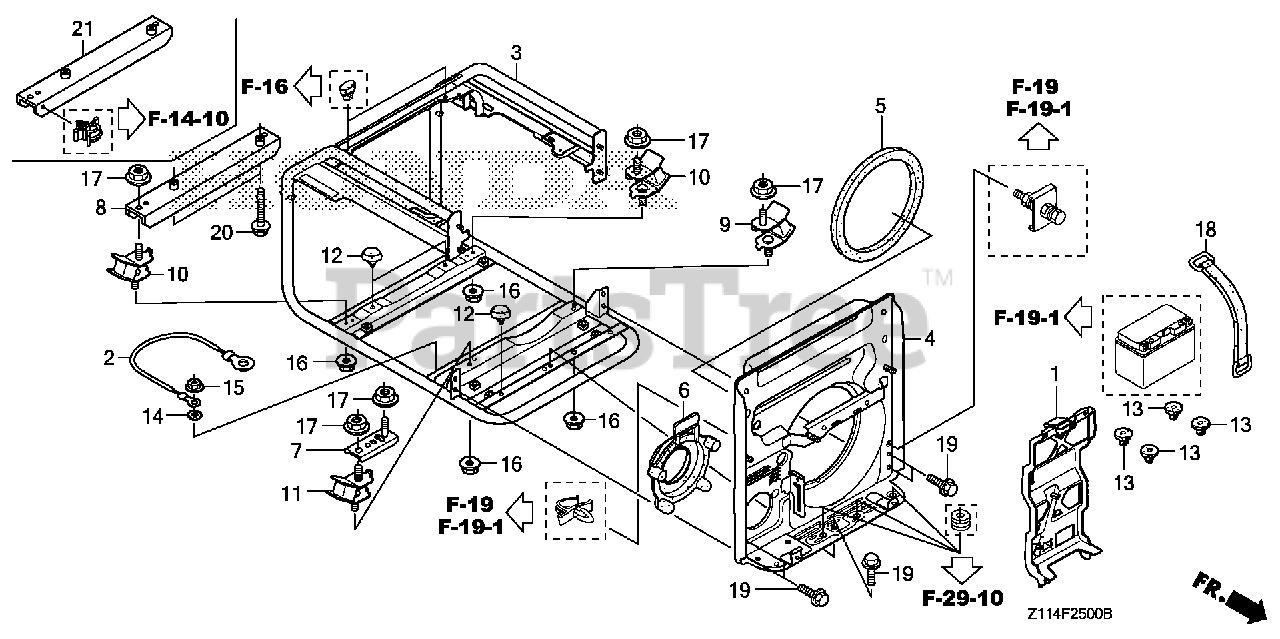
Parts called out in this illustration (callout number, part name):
1	BRACKET, WIRE HARNESS CLIP
2	CABLE, SUB-GROUND
3	FRAME *NH105* (MAT BLACK)
4	FRAME, FR.
5	RUBBER A, SEPARATOR SEAL
6	RUBBER B, SEPARATOR SEAL
7	BRACKET, FR. ENGINE MOUNT *NH105* (MAT BLACK)
8	BRACKET, RR. ENGINE MOUNT
9	RUBBER (LOWER)
10	RUBBER (LOWER)
11	RUBBER, L. (LOWER)
12	RUBBER, STOPPER
13	RUBBER, BATTERY BOX
14	WASHER, LOCK (6MM)
15	NUT, FLANGE (6MM)
16	NUT, FLANGE (8MM)
17	NUT, FLANGE (10MM)
19	BOLT, FLANGE (8X12)
20	BOLT, FLANGE (8X30)
